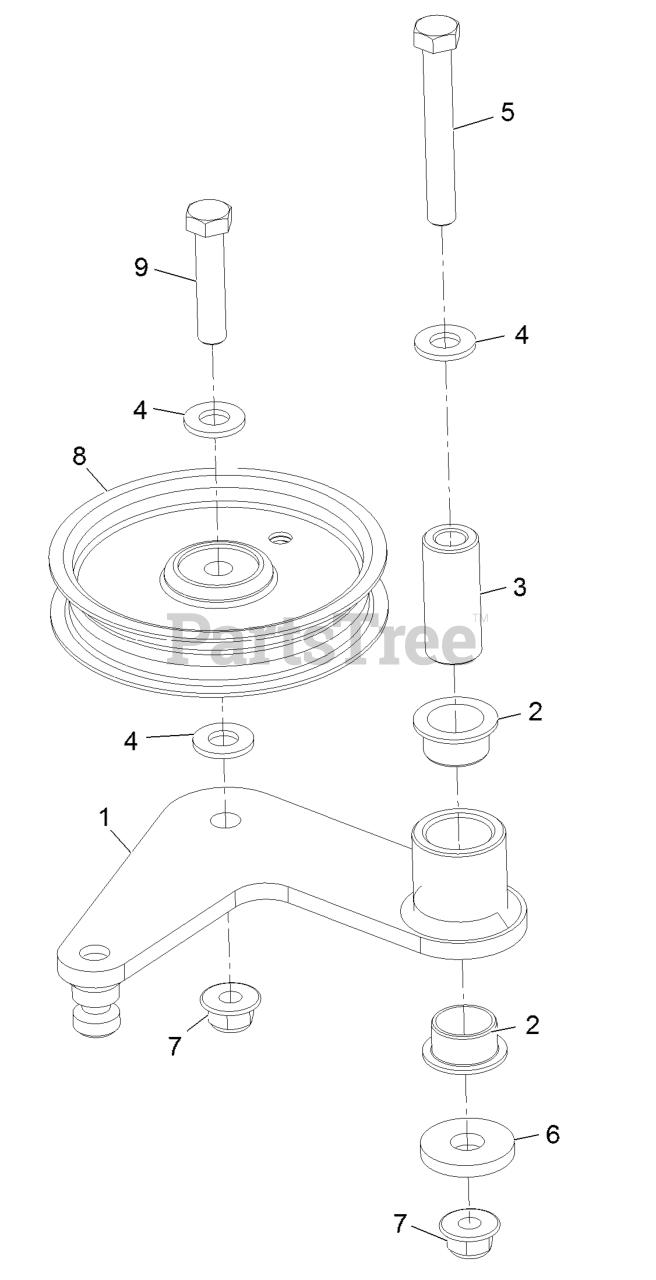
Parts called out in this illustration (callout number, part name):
1	Idler Arm ASM
2	Bushing-Flanged
3	Spacer, Pivot
4	Washer-3/8 SAE
5	Screw-HH 3/8-16 X 2 3/4
7	Nut-Nyloc 3/8-16 Flg
8	Pulley-Idler
9	Screw-HH 3/8-16 X 1 3/4
